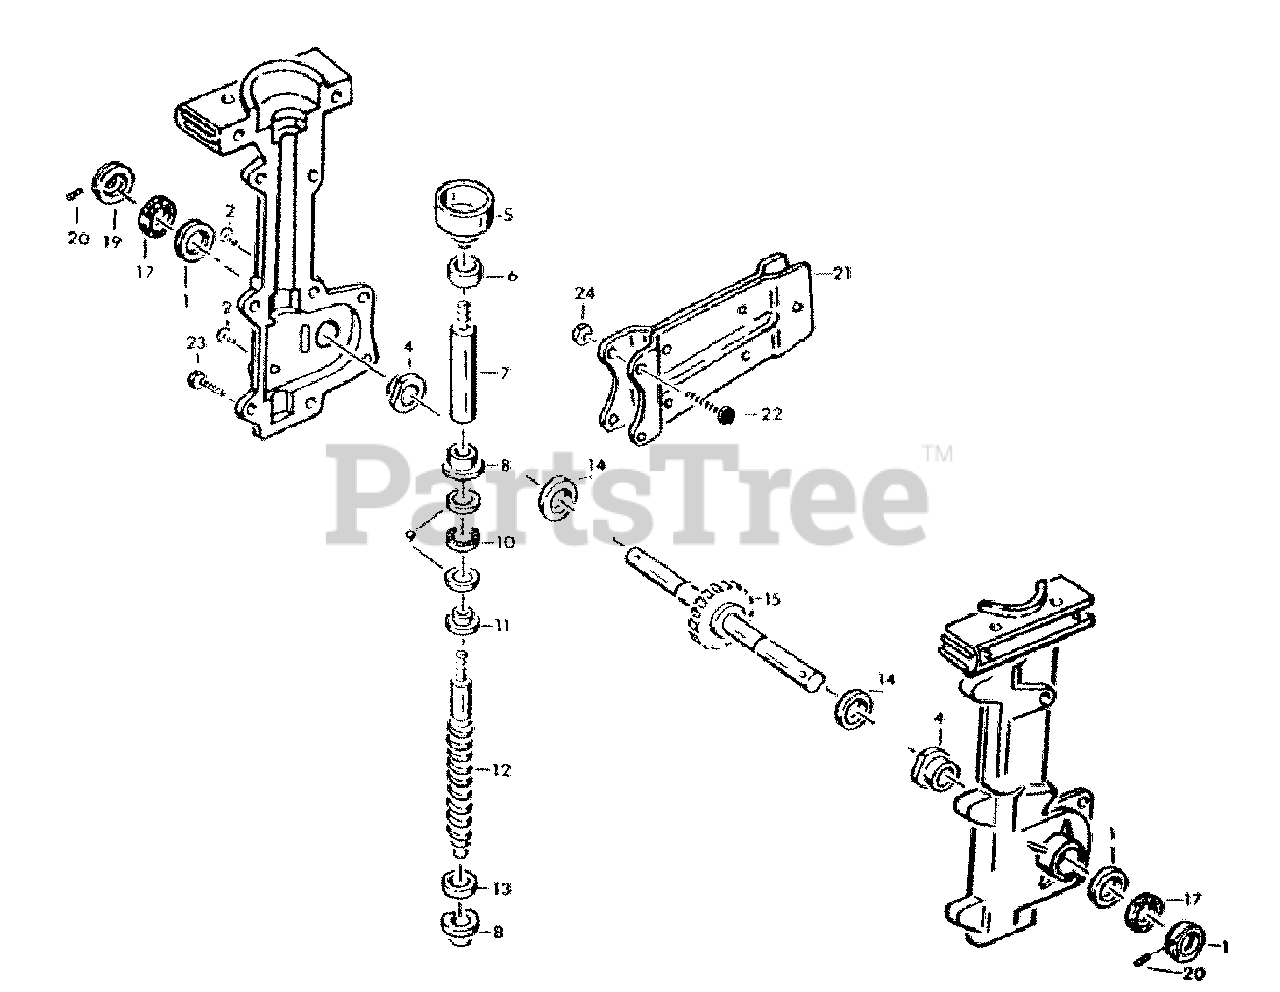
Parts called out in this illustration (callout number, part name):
2	Screw, Phillips Pan Hd 1/4-20 x 1/2
4	Bushing, Bronze
5	Drum & Hub, Clutch
6	Bearing, Roller
7	Shaft, Connecting
8	Bushing, Bronze
9	Washer, Thrust
10	Bearing, Needle, Thrust
11	Washer, Adaptor
12	Shaft, Worm
13	Washer, Thrust
14	Washer, Thrust
15	Shaft, Tine, w/Worm Wheel
19	Dirt Cap, Silver, Metal
20	Set Screw, # 10-32 x 1/4
21	Bracket Assy, Drag Stake
22	Screw, 1/4-20 x 1
23	Screw, 1/4-20 x 7/8
24	Nut, 1/4-20
24	Transmission Assembly, Complete
